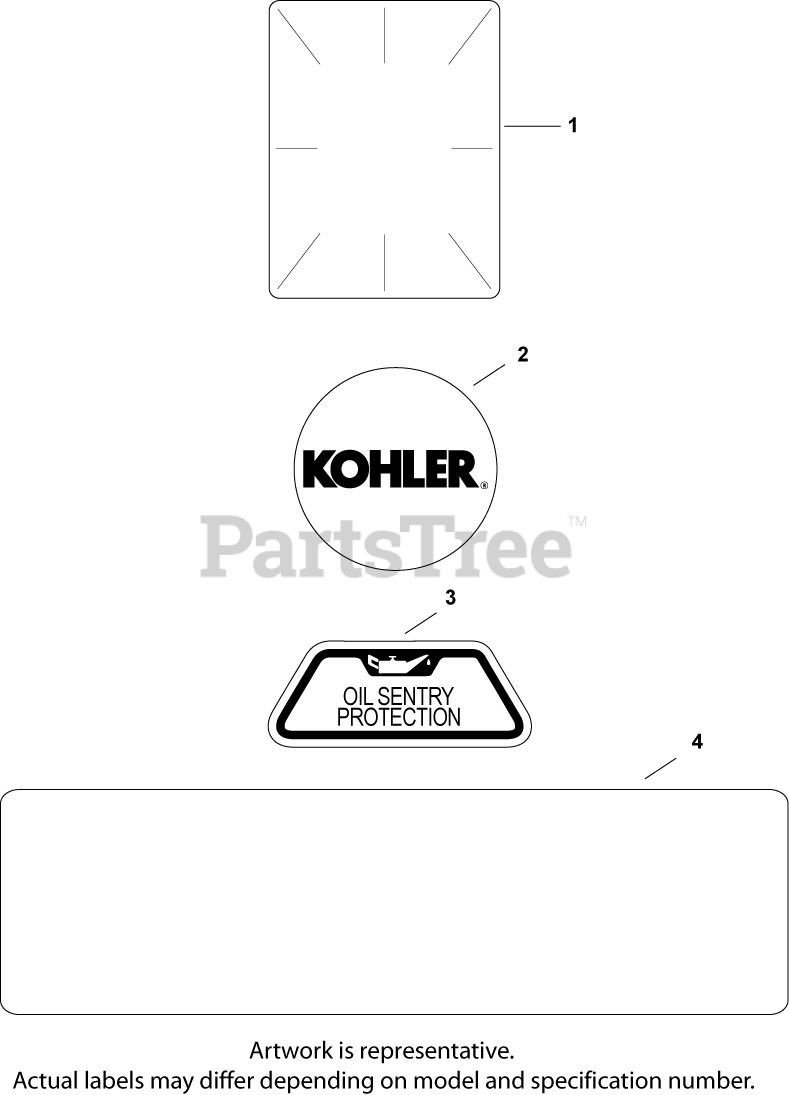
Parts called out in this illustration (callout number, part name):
1	DECAL, CLEAR LAMINATE USE 25 113 70-S
2	DECAL, GRASS SCREEN USE 24 113 499-S
3	DECAL, OIL SENTRY - (#DSC)
4	DECAL, 18 HP
